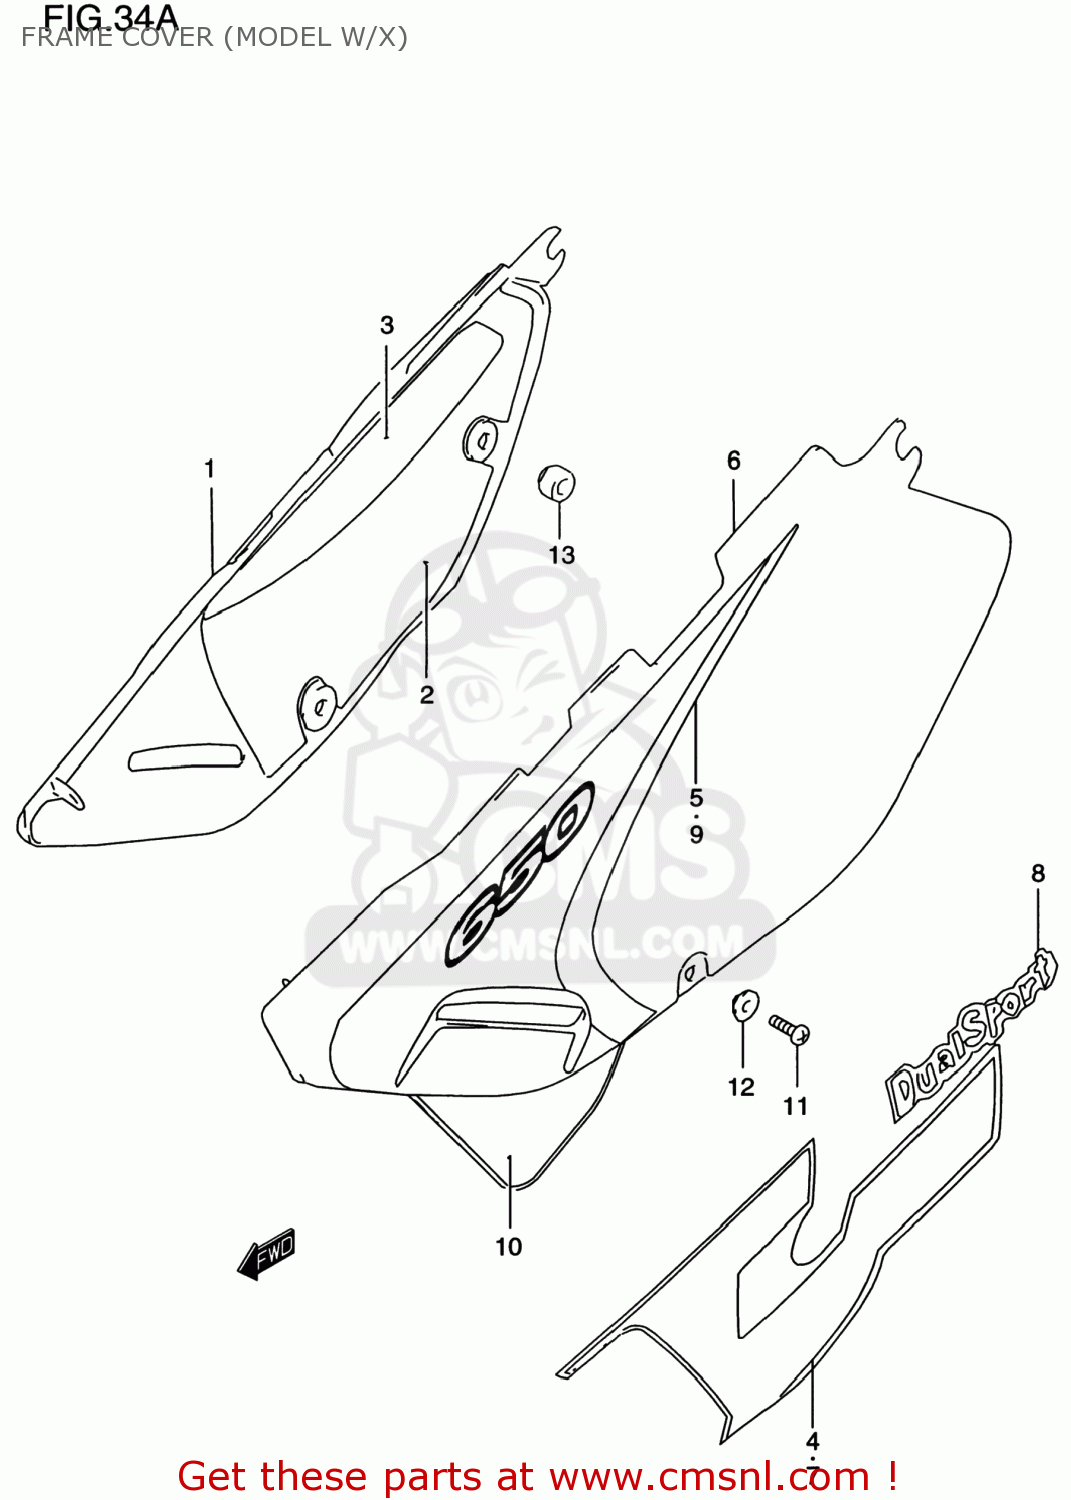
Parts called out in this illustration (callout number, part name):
1	COVER,FRAME,RIGHT
2	SHIELD,FRAME COVER,R NO.1
3	SHIELD,FRAME COVER,R NO.2
4	TAPE,FRAME COVER,RIGHT
5	TAPE,FRAME COVER,R
6	COVER,FRAME,LEFT
7	TAPE,FRAME COVER,LEFT
8	EMBLEM,FRAME COVER
9	TAPE,FRAME COVER,L
10	TAPE,LWR
11	SCREW
12	WASHER
13	CUSHION
